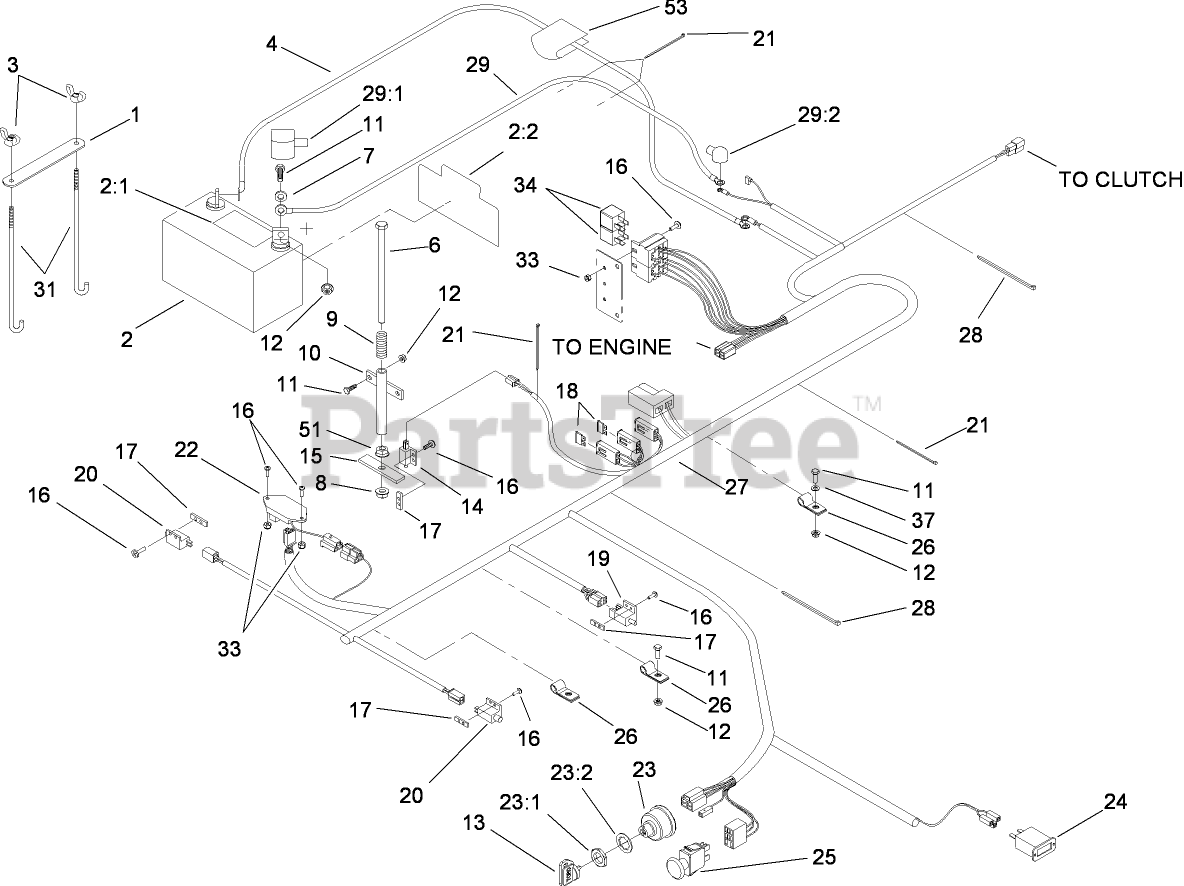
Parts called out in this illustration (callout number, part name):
1	STRAP-HOLDDOWN, BATTERY
2	BATTERY
2:1	Decal-Battery
2:2	Decal-Battery
3	WINGNUT
4	WIRE-GROUND
6	SCREW-HH
7	WASHER-FLAT
8	NUT-LOCK, NI
9	SPRING-SWITCH, SEAT
10	MOUNT-SPRING, SEAT
11	SCREW-HH
12	NUT-HF
13	KEY-IGNITION
14	SWITCH-CLOSED, NORMALLY
15	PLATE-SWITCH, SEAT
16	SCREW-PPH
17	PLATE-TAPPED
18	FUSE-BLADE TYPE, 20 AMP
19	SWITCH
20	SWITCH-OPEN, NORMALLY
21	TIE-CABLE
22	MODULE-DELAY, SEAT
23	SWITCH ASM
23:1	NUT-HH
23:2	WASHER-TOOTH, INTERNAL
24	METER-HOUR
25	SWITCH-PTO
26	CLIP-LOOM
27	Harness-Wire
28	TIE-PLASTIC
29	POSITIVE BATTERY CABLE ASM
29:1	INSULATOR-BATTERY
29:2	INSULATOR-SOLENOID
31	BOLT-HOLDDOWN
33	NUT-LOCK, NI
37	WASHER-FLAT
51	NUT-HEX
53	DECAL-INSTRUCTIONS, CHARGING
